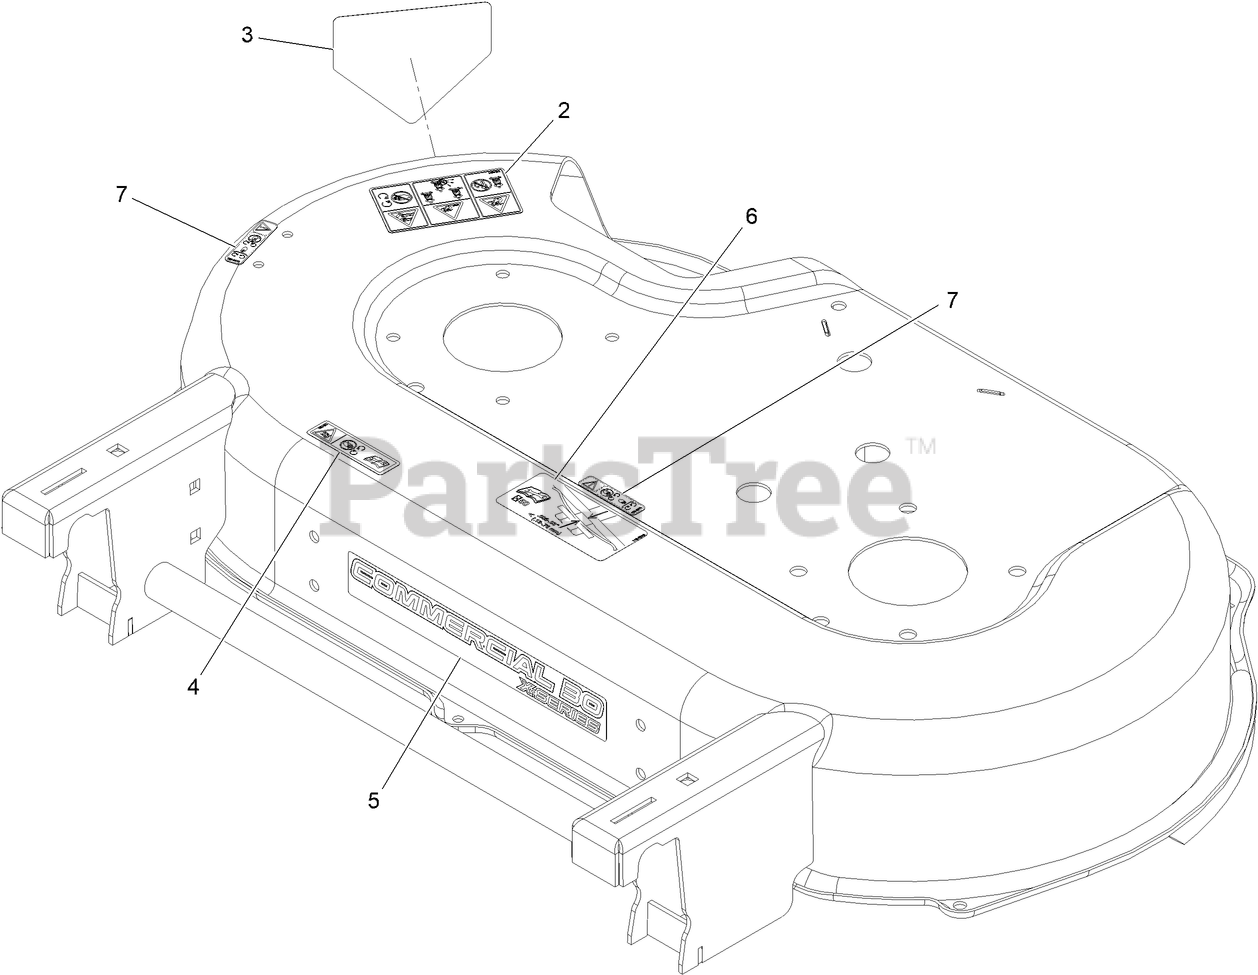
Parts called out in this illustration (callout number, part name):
2	DECAL-DANGER, CE
3	DECAL-DANGER
4	DECAL-WARNING
5	DECAL-COMM 30 X-SERIES
7	DECAL-WARNING
